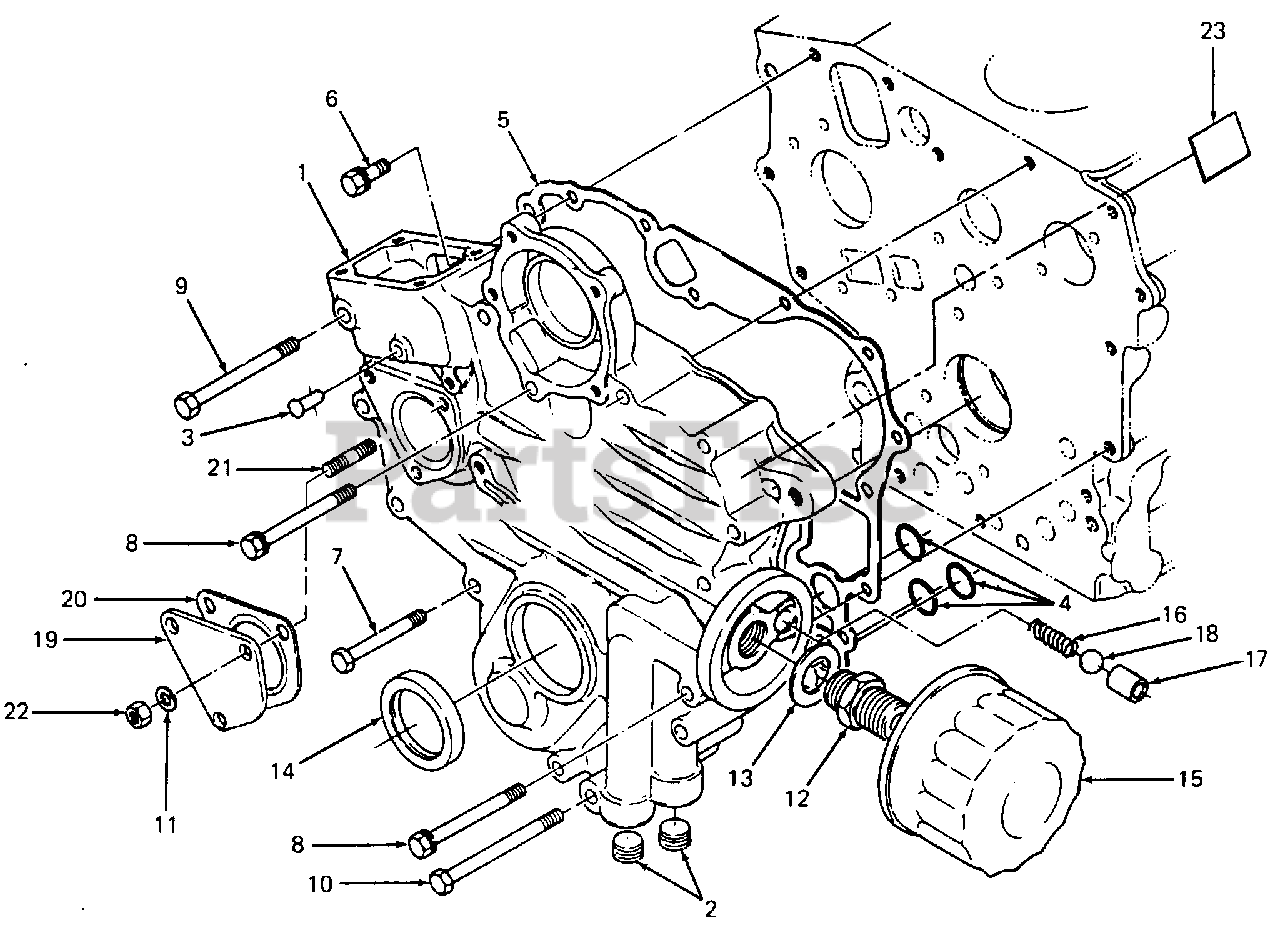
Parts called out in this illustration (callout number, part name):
1	Case Assy, Gear
4	O-Ring, 1/2 X 11/16
5	Gasket, Gear Case
6	Screw, Hex Cap w/Washer
7	Screw, Hex Cap
8	Screw, Hex Cap w/Washer
9	Screw, Hex Cap
10	Screw, Hex Cap
11	Washer, Spring
15	Element, Filter
18	Ball, Metal, 11/32 Dia
